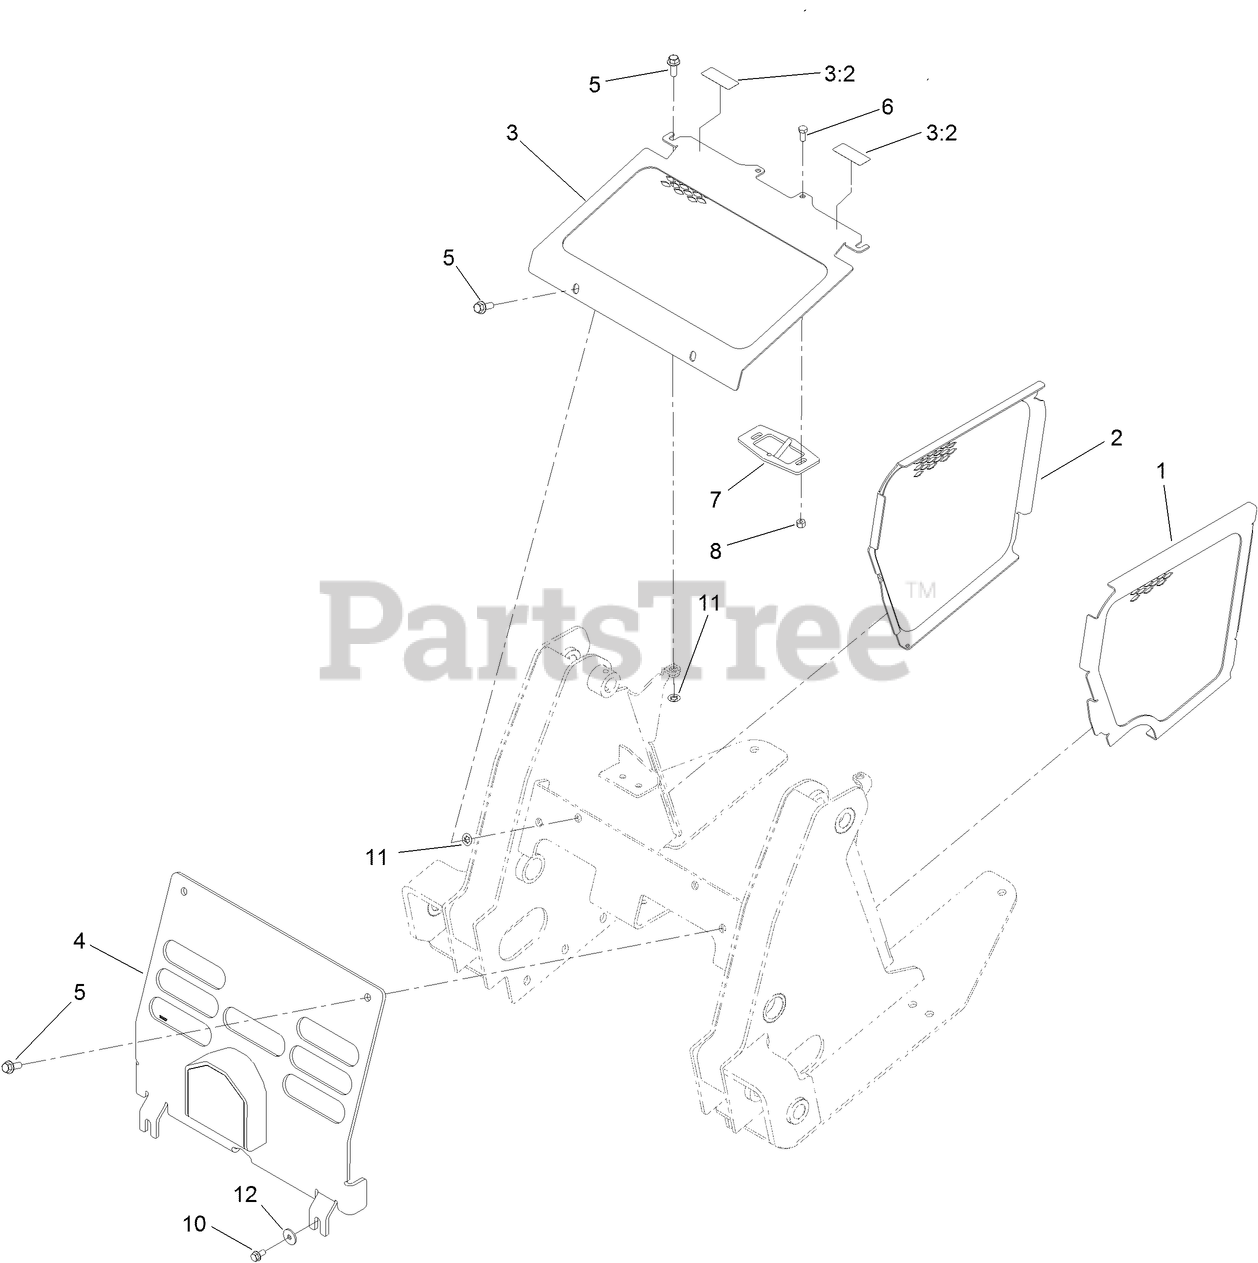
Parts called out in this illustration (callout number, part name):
1	PANEL-SIDE, LH
2	PANEL-SIDE, RH
3	COVER-TOP
3:2	DECAL-SURFACE, HOT
4	COVER-FRONT
5	SCREW-HHF
6	SCREW-HH
7	HOOD LATCH/ROD ASM
8	NUT-LOCK, NI
10	SCREW-HHF
11	NUT-PUSH
12	WASHER-FLAT
